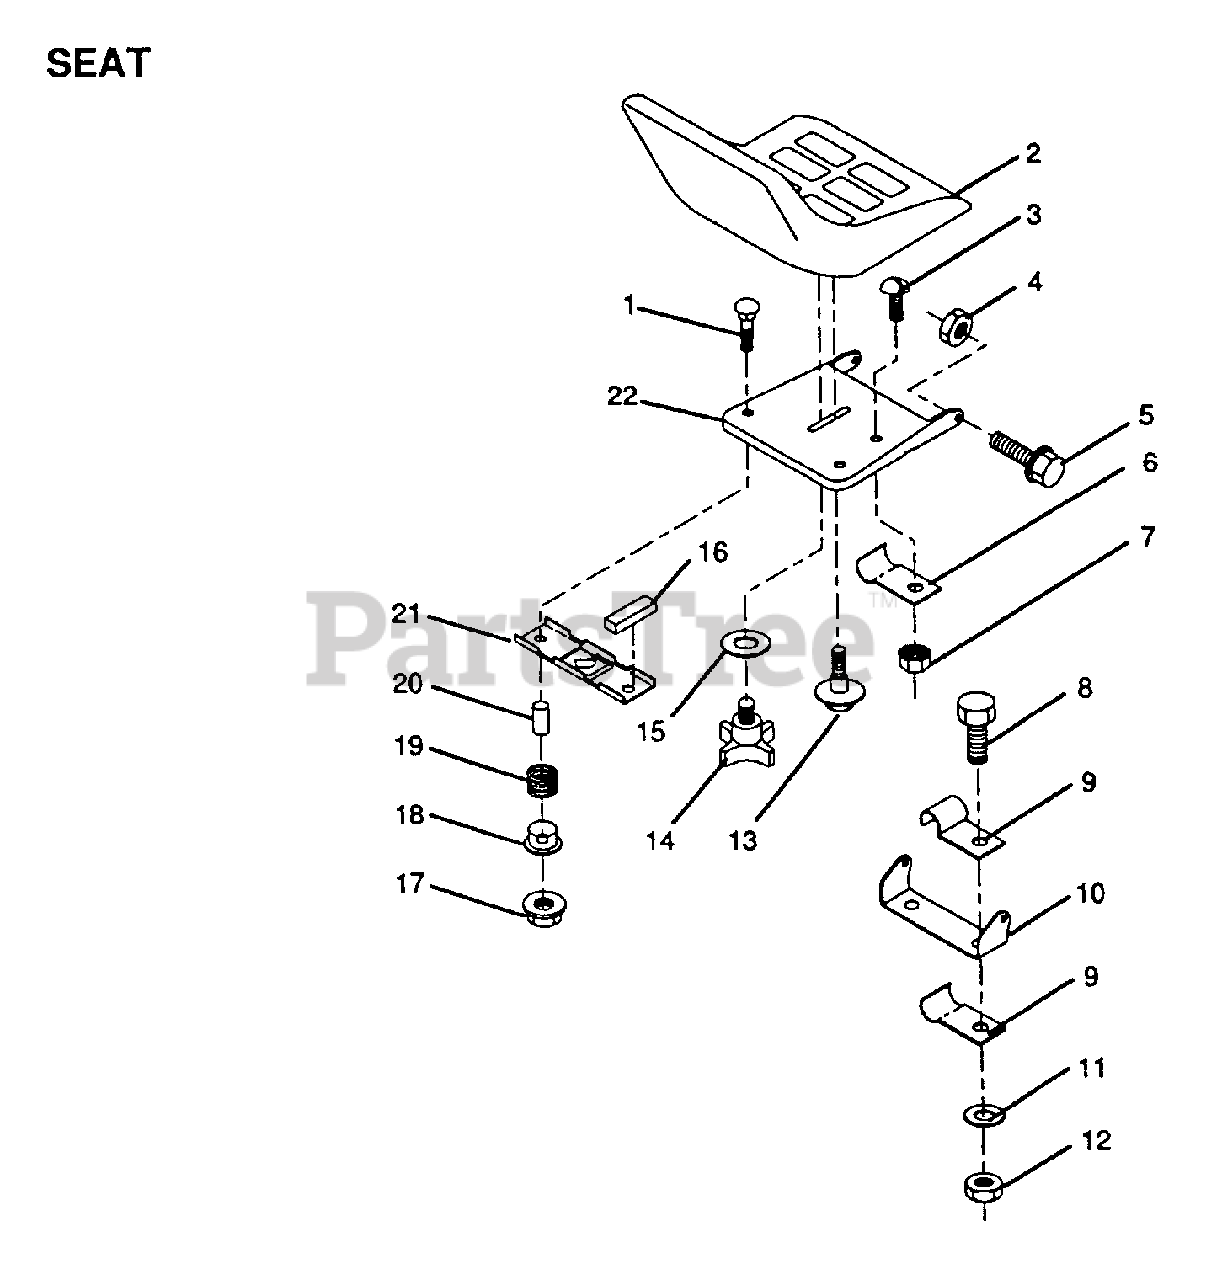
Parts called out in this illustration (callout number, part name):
1	BOLT
9	CLIP T
11	WASHER
14	"KNOB 1/2"" YT"
15	WASHER
16	STRIP FORM
18	BUSHING
19	SPRING
20	SPACER SPLIT
21	BRKT SWITCH
